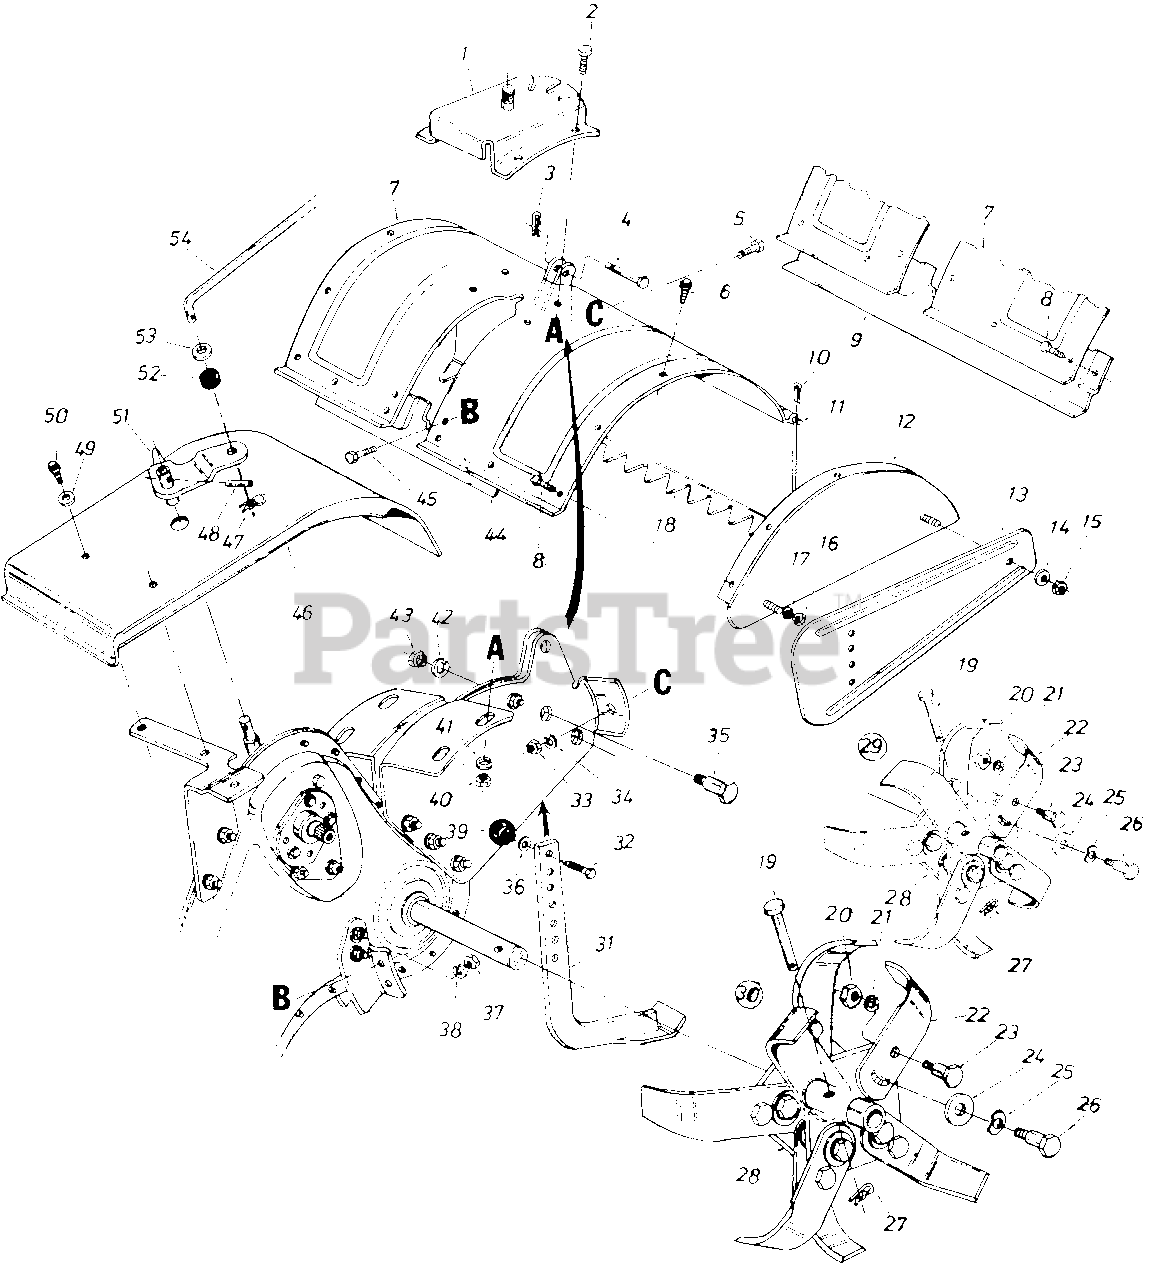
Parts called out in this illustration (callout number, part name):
1	Handle Positioner Brkt. Ass'y.
2	Hex Bolt 3/8-16 x .75" Lg.*
3	Intern. Cotter Pin 5/16" Dia.
4	Clevis Pin .375" Dia.
5	Hex Bolt 5/16-18 x .75" Lg.*
6	Hex Wash. Tap Scr.
8	Hex Bolt 5/16-18 x .75" Lg.*
9	Bracket Reinforcement-18"
10	Cotter Pin 3/32" Dia. x .75" Lg.*
11	Tiller Flap Rod
15	Hex Nut 5/16-18 Thd.*
16	Hex Nut 5/16-18 Thd.*
17	L-Wash. 5/16" I.D.*
19	Clevis Pin .375" Dia.
20	Hex Nut 3/8-24 Thd.*
21	L-Wash. 3/8" I.D.-H.D.
23	Shld. Bolt 1/2" Dia. x .175
24	Fl-Wash. .51" I.D. x 1.50" O.D.
25	Bell-Wash. .515" I.D. x 1.14" O.D.
26	Shld. Bolt 1/2" Dia. x .320
27	Intern. Cotter Pin
29	R.H. Tine Ass'y Comp. 14"
32	Hex Bolt 3/8-16 x .75" Lg.*
33	Hex Nut 5/16-18 Thd.*
34	L-Wash. 5/16" I.D.*
35	Shld. Bolt 1/2" I.D. x .62" Lg.
36	Fl-Wash. 3/8" I.D. x 518" O.D.
37	Hex Nut 5/16-18 Thd.*
38	L-Wash. 5/16 I.D.*
39	Ball Knob
40	Hex Nut 3/8-16 Thd.*
41	L-Wash. 3/8" I.D.*
42	L-Wash. 3/8" I.D.*
43	Hex Nut 3/8-16 Thd.*
44	Bracket Reinforcement- 14"
45	Hex Bolt 5/16-18 x .75" Lg.*
46	Shift Cover
47	Intern. Cotter Pin 5/16" Dia.
48	Spring Roll Pin 3/16" Dia. x 1.00" Lg.
49	Fl-Wash. .281" I.D. x .62" O.D.
50	Hex Wash. Self-Tap Scr. 1/4-20 x .50" Lg.
51	Shifting Crank Ass'y. D x 2.05
52	Rubber Washer .33" I.D. x .87" O.D.
53	Fl-Wash. .400" I.D. x 1.250" O.D.
54	Control Rod .33" Dia. x 37" Lg.
